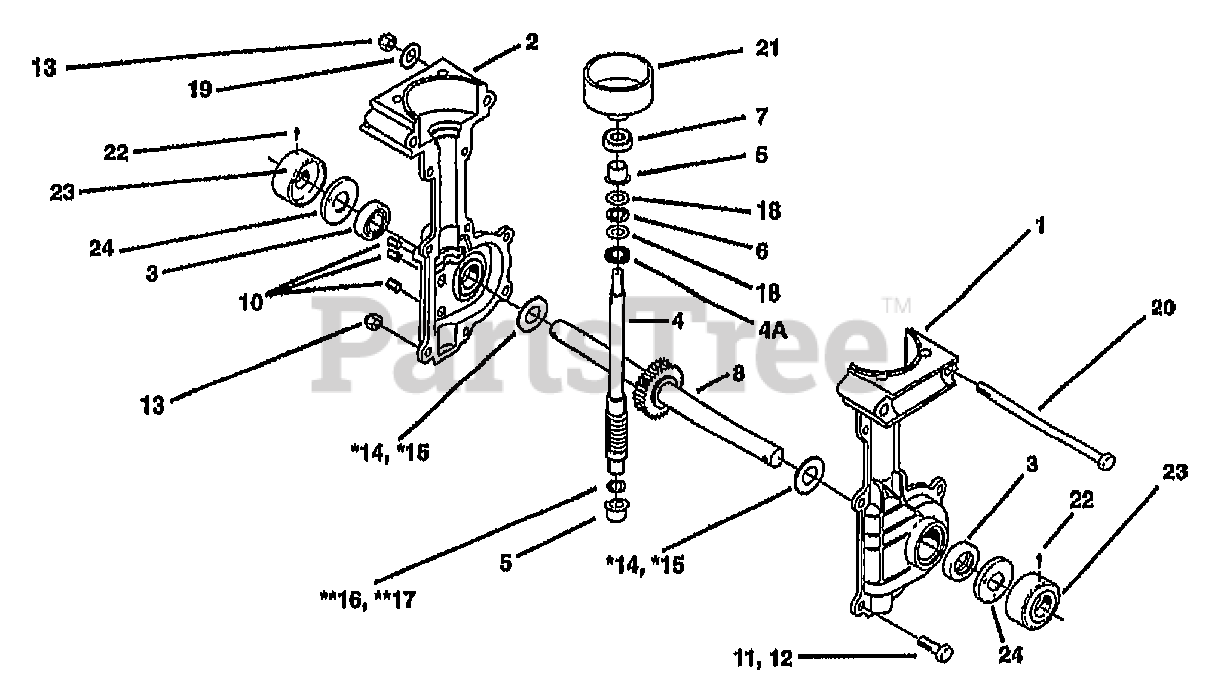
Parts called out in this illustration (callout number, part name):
1	ASSM-TRANS CASE LEFT
2	ASSM-TRANS CASE RIGHT
3	SEAL-PINION SHAFT PT/85030/00
4	SHAFT-WORM PT/85032/00
4A	SEAL-OIL INPUT SHAFT
5	BEARING-INPUT
6	BEARING-THRUST PT/85034/00
7	BEARING-BALL PT/85035/00
8	ASSM-SHAFT OUTPUT AS/85037/00
10	PLUG-PIPE 1/8 NPT
11	SCR-HH 1/4-20 X .875
12	SCR 1/4-20X1.125
13	NUT-LK 1/4-20
14	WASHER-THRUST .775X.05 (.050")
15	WASHER-THRUST .775X.05 (.040")
16	WASHER-THRUST .505X.02 (.020")
17	WASHER-.76X.5X.04 THRUST (.025")
18	WASHER-THRUST .92X.5X.06
19	WASHER-.75X.312X.065 ZP
20	SCR-HH 1/4-20X5
21	ASSM-CLUTCH & DRUM
22	SCR M10-32X.25
23	KIT-DUST CAP
24	WASHER-FELT 1.5X.72X.13
